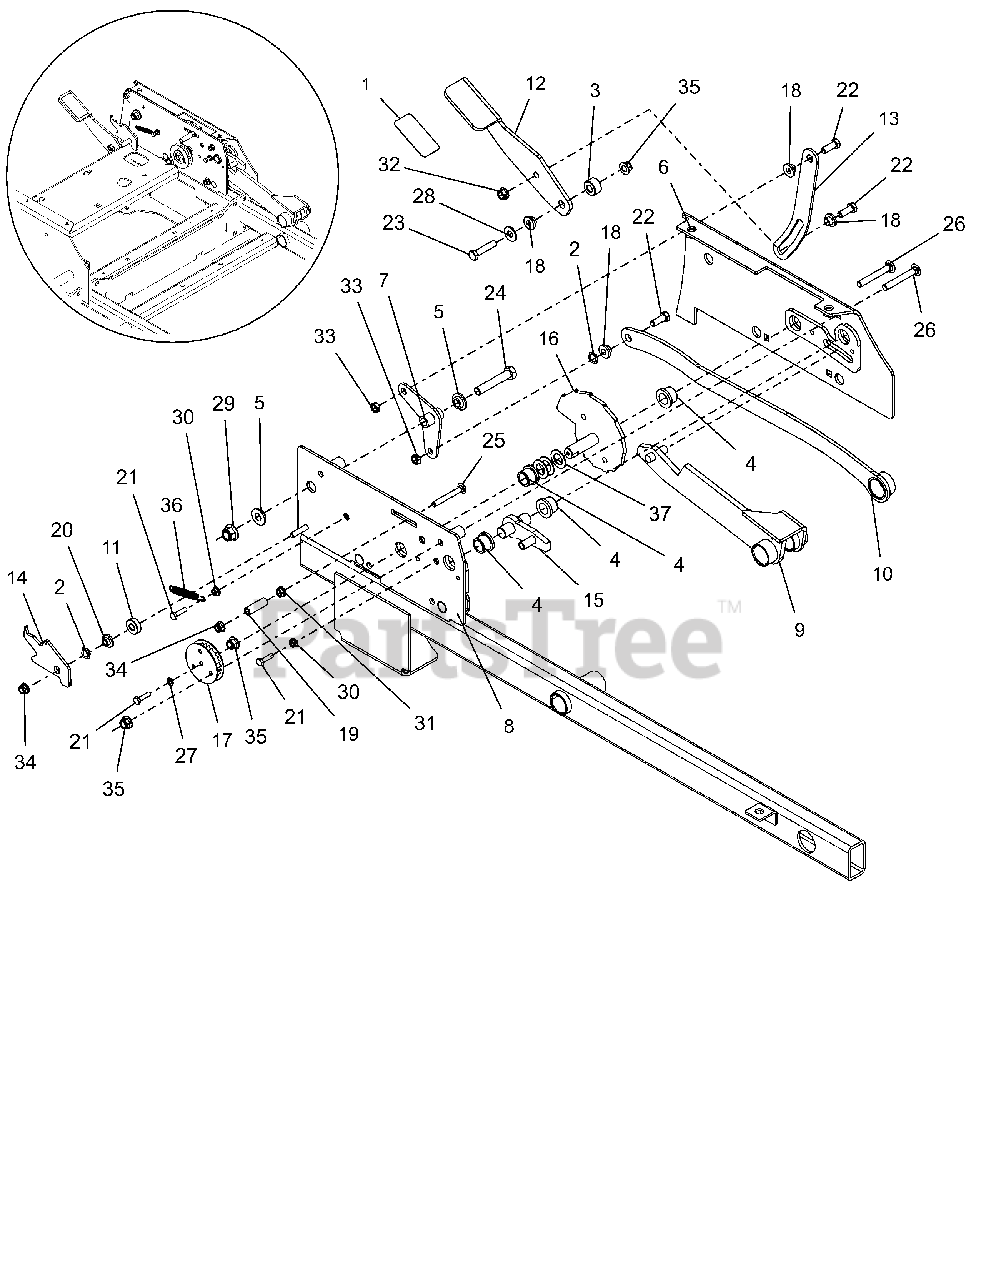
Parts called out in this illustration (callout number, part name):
1	GRIP, PEDAL 1.50 X 3.00
2	WAVE WASHER .531X.781X.125FH
3	SPACER, .437X1.00X.58 SMLS
4	BUSHING, FLANGE .75X.75X1.0
5	BSHG-FLG .515X.750X.310X1.120
6	SIDE, LH BOTTOM TOWER
7	WLDMT, REAR PIVOT
8	WLDMT, CAM COVER
9	WLDMT, CAM CONTACT
10	WLDMT, DECK LIFT LINK
11	SPCR, .375 X 1.00 X .342
12	PEDAL, DECK LIFT
13	LINK, DECK LIFT PEDAL
14	LATCH, FOOT PEDAL
15	WLDMT, DECK LOCK
16	WLDMT, HEIGHT OF CUT
17	WLDMT, LOWER PULLEY
18	BSHG-FLG .385X.500X.875X.406
19	BSHG-SLV .325X.49X1.56
20	BSHG-FLG .32X.500X.344X.880
21	@BLT-HEX .25-20X1.00 GR5 YWZC
22	@BLT-HEX .38-16X1.00 GR5 YWZC
23	@BLT-HEX .38-16X1.75 GR5 YWZC
24	@BLT-HEX .50-13X2.75 GR5 YWZC
25	@BLT-RDHDSQNK .31-18X2.50 G5YZ
26	@BLT-RDHDSQNK .38-16X2.75 G5YZ
27	@WSHR-LK .25X.062 REG YWZC
28	@WSHR-FL-STL.438X1.00X.083 YWZ
29	@NUT-LK-NYL-FLG .50-13 YWZC
30	@NUT-SPNLK-FLG .25-20 YWZC
31	@NUT-SPNLK-FLG .312-18 YWZC
32	NUT-LK-CTR-FLG .38-16 YWZC
33	@NUT-LK-CTR-JAM .375-16 YWZC
34	@NUT-LK-NYL-FLG .31-18 YWZC
35	@NUT-LK-NYL-FLG .38-16 YWZC
36	SPRING, EXTENSION
37	WSHR-FL-STL .750X1.250X.048 YZ
